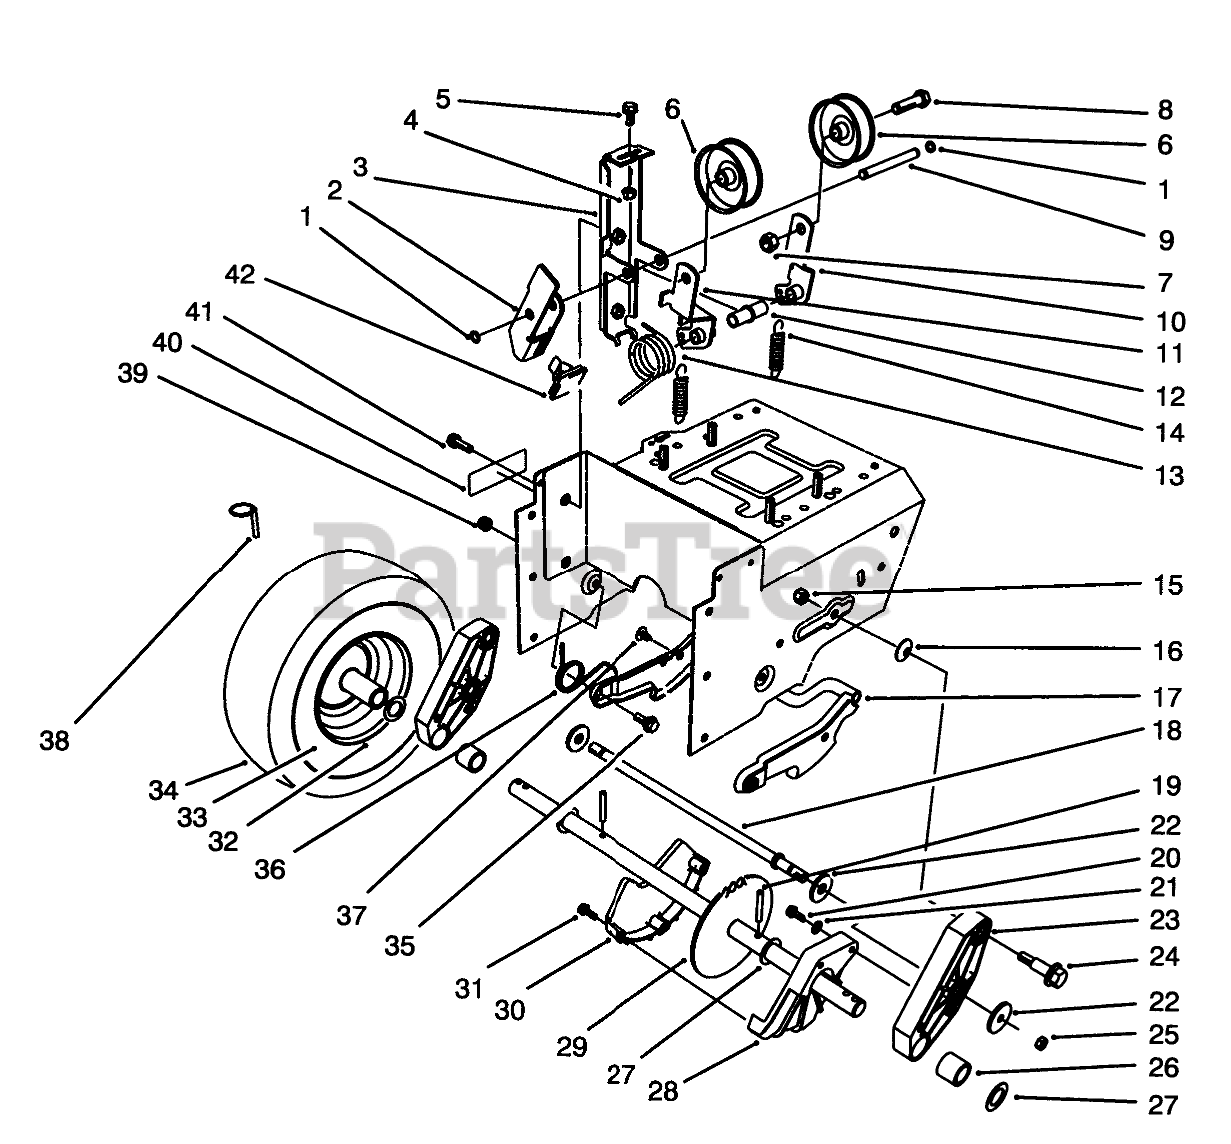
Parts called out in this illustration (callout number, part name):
1	RING-RETAINING
2	ARM-BRAKE
3	IDLER ARM BRACKET ASM
4	NUT-LOCK, NI
5	SCREW-HHF
6	PULLEY-IDLER
7	NUT-LOCK, NI
8	SCREW-HH
9	PIN-IDLER
10	ARM-IDLER, TRACTION
11	ARM-IDLER, IMPELLER
12	BUSHING-IDLER
13	TORSION SPRING
14	SPRING-EXTENSION
15	NUT-LOCK, NI
16	WASHER-SPRING
17	Latch-Arm
18	ROD-LATCH
19	PIN-ROLL, SLOTTED
20	SCREW-HWH
21	WASHER-FLAT
22	WASHER-SUPPORT
23	Pivot Arm Assembly (Incl. Ref. #26)
24	BOLT-SHOULDER
25	NUT-LOCK, NI
26	BUSHING-AXLE
27	WASHER-THRUST
28	GUARD-CHAIN, LH
30	GUARD-CHAIN, RH
31	Screw
32	RIM-WHEEL
33	INNER TUBE
35	SCREW-SHOULDER
36	SPRING-LATCH, TORSION
37	FASTENER-PANEL
38	PIN-LYNCH
39	NUT-LOCK, NI
40	DECAL-WARNING
41	SCREW-HHF
42	PAD-BRAKE
